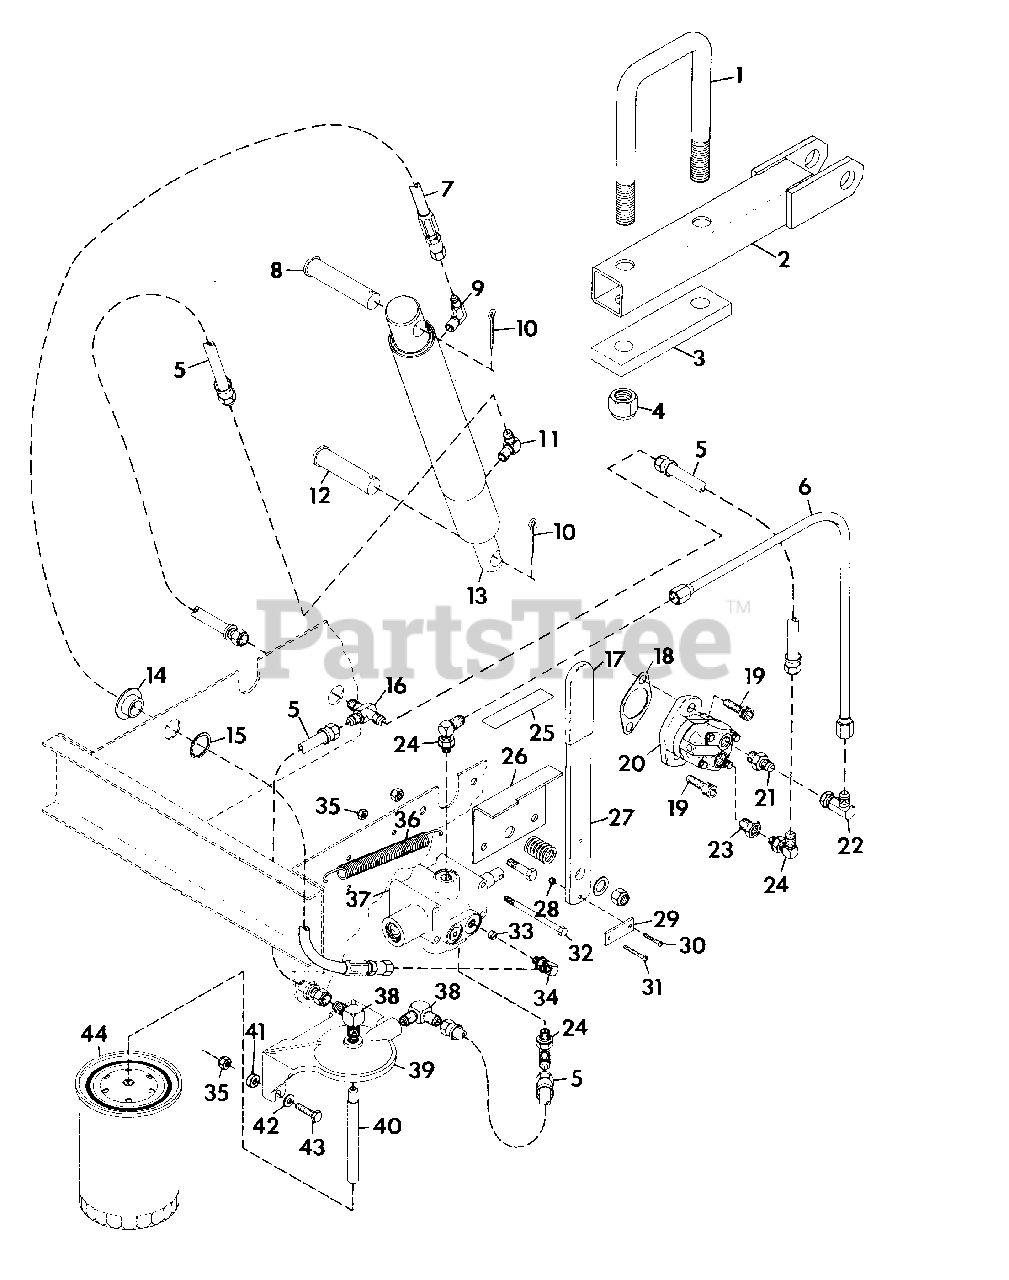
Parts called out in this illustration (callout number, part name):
1	U-Bolt
2	Arm, Lift
3	Plate, Axle
4	Nut, Lock 5/8-18
5	Hose, Hydraulic
6	Line, Hydraulic Pump to Valve
7	Hose, Hydraulic
8	Pin, Clevis
9	Adaptor
10	Pin, Cotter .125x1.25
11	Adaptor, Hydraulic
12	Pin, Clevis
13	Cylinder, Hydraulic
14	Bushing, Nylon .76x1x.6 Flange
15	Ring, Retaining Internal Tooth
16	Adaptor, Tee
17	Grip, Handle
18	Gasket, Cover Plate
19	Screw, Cap 3/8-16 Hex Socket Head
20	Pump, Hydraulic
21	Adaptor
22	Adaptor
23	Bushing
24	Adaptor
25	Decal, Hydraulic Lift
26	Bracket, Lift
27	Lever, Lift
28	Nut, Lock 10-24
29	Strap, Valve
30	Screw, Machine 10-24x.75 Rd Hd
31	Screw, Machine 10-24x1.00 Rd Hd
32	Bolt, Hex 1/4-20x2.75
33	Plate, Flow Restriction
34	Adaptor
35	Nut, Lock 1/4-20
36	Spring, Extension 5.5x.5x20 Rate
37	Valve, Control
38	Adaptor
39	Bracket, Oil Filter
40	Tube, Oil Pickup
41	Spacer
42	Washer, Flat .312x.734x.065
43	Bolt, Hex 1/4-20x1.25
44	Filter, Spin-On
